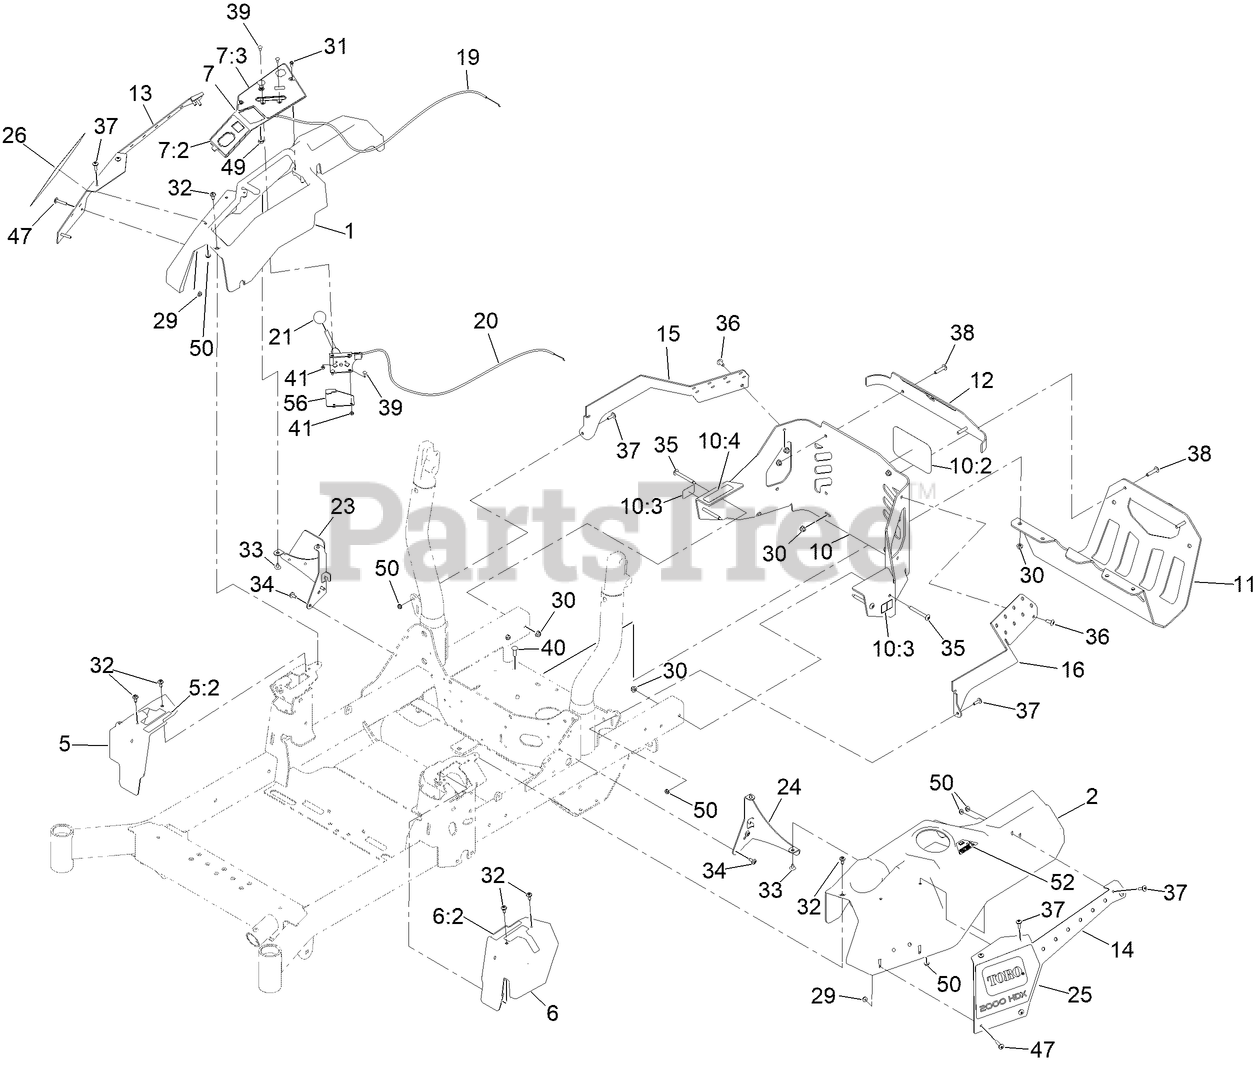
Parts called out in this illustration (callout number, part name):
1	CONSOLE-RH
2	CONSOLE-LH
5	COVER-CONTROL, MOTION (RH)
5:2	DECAL-CONTROL, MOTION (RH)
6	COVER-CONTROL, MOTION (LH)
6:2	DECAL-CONTROL, MOTION (LH)
7	CONTROL PANEL ASM
7:2	DECAL-PANEL, CONTROL
7:3	DECAL-PANEL, CONTROL
10	REAR GUARD ASM
10:2	DECAL
10:3	DECAL-WARNING
10:4	DECAL-ARRESTOR, SPARK
11	GUARD-MUFFLER [BLACK]
12	TRIM-UPPER REAR
13	COVER,POD RH
14	COVER [BLACK]
15	BRACKET-GUARD, RH
16	BRACKET-GUARD, LH
19	CABLE-CONTROL, CHOKE
20	CABLE-CONTROL, THROTTLE
21	KNOB-BALL
23	SUPPORT-CONSOLE, RH
24	BRACKET-CONSOLE, LH
25	DECAL - HDX
26	DECAL - HDX
29	NUT-HF
30	NUT-HF, NI
31	SCREW-HWH
32	SCREW-SHOULDER
33	SCREW-TORX
34	SCREW-TORX
35	SCREW-TORX
36	SCREW-TORX
37	SCREW-TRUSS
38	SCREW-TORX
39	BOLT-CARR
40	SCREW-CARR
41	NUT-LOCK, NI
47	SCREW-TRUSS
49	NUT-HJ
50	NUT-KEPS
52	DECAL-FILL, FUEL
56	BRACKET-SET, THROTTLE
